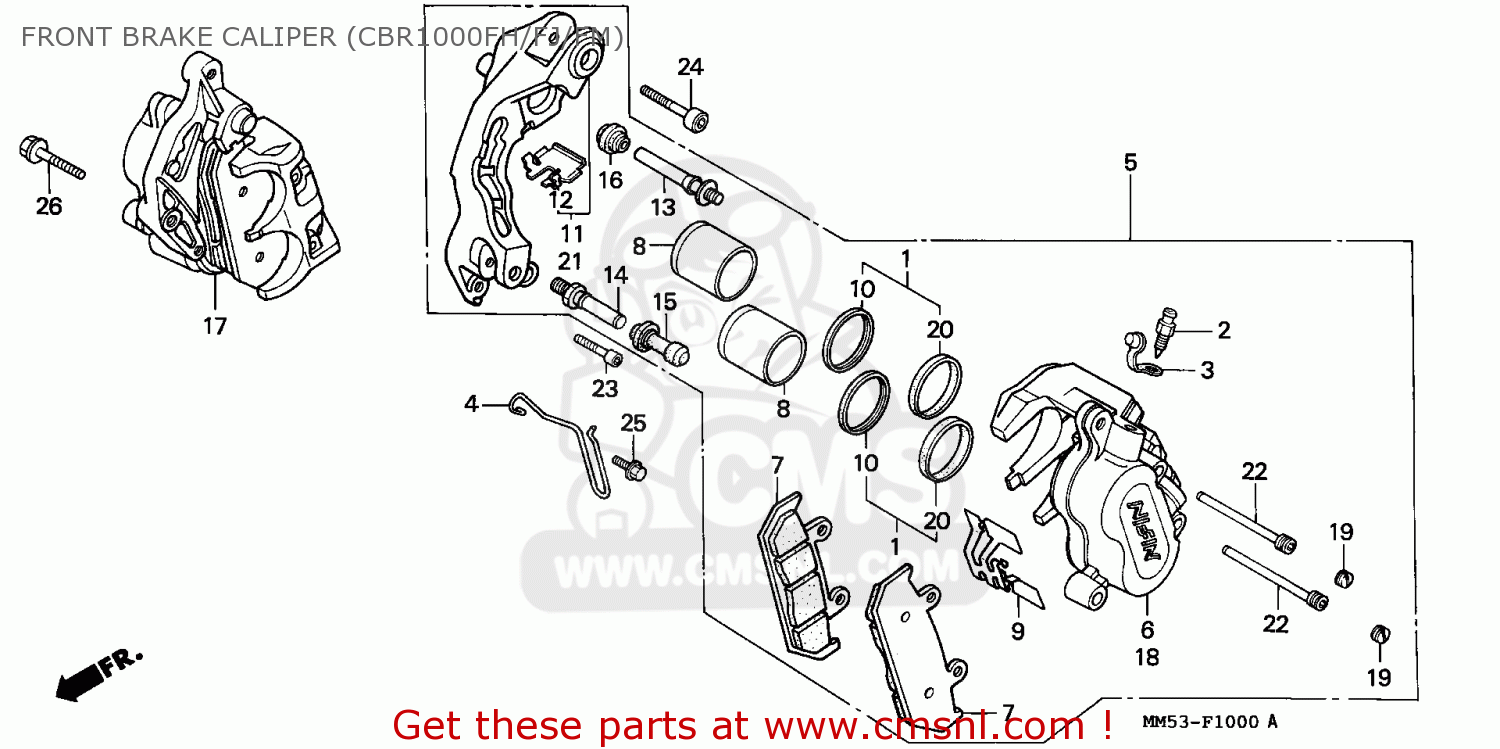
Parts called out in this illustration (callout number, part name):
2	SCREW, BLEEDER
3	CAP,BLEEDER
4	CLAMP,SPEDMT.CABL
5	CALIPER ASSY.,L.F
6	CALIPER COMP.,L.(
7	PAD COMP.A (NISSI (MCA)
8	PISTON COMP.
9	SPRING,PAD
10	DUST SEAL
11	BRACKET COMP.,L.
12	RETAINER
13	BOLT A,PIN
14	PIN,BOLT
15	BUSH,PIN
16	BOOT B
17	CALIPER ASSY.,R.F
18	CALIPER COMP.,R.
19	PLUG,PIN
20	SEAL,PISTON
21	BRACKET COMP.,R.
22	PIN HANGER
23	BOLT SOCKET 6X24
24	BOLT,SOCKET,8X36
25	BOLT,FLANGE,6X10
26	BOLT,FLANGE,DR.8X
